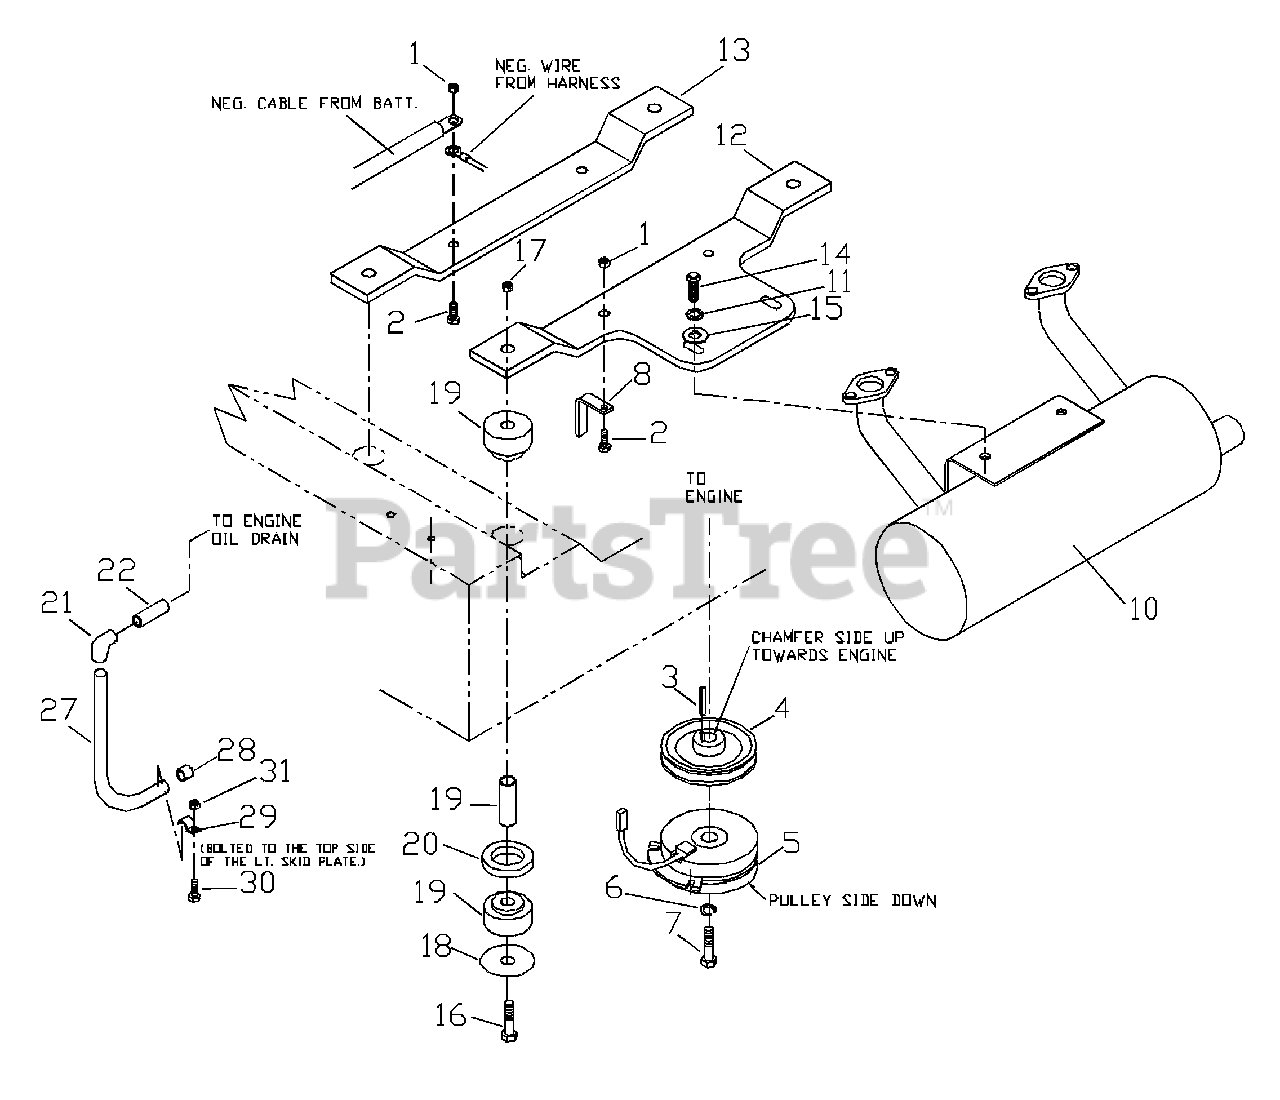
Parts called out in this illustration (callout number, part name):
1	NUT 5/16 LOCK
2	HCS 5/16 X 1.75
3	KEY 1/4 SQ.
6	WASHER 7/16 LOCK
7	HCS 7/16F X 2.5
8	CLUTCH TIE DOWN
11	WASHER 5/16 LOCK
12	ENGINE MOUNT
13	ENGINE MOUNT
14	HCS 5/16 X .750
15	WASHER 5/16 FLAT
16	HCS 1/2 X 3.25
17	NUT 1/2 NYLOC
22	3/8 NPT PIPE
27	OIL DRAIN HOSE
30	HCS 1/4 X .750
31	NUT 1/4 CTR. LOCK
